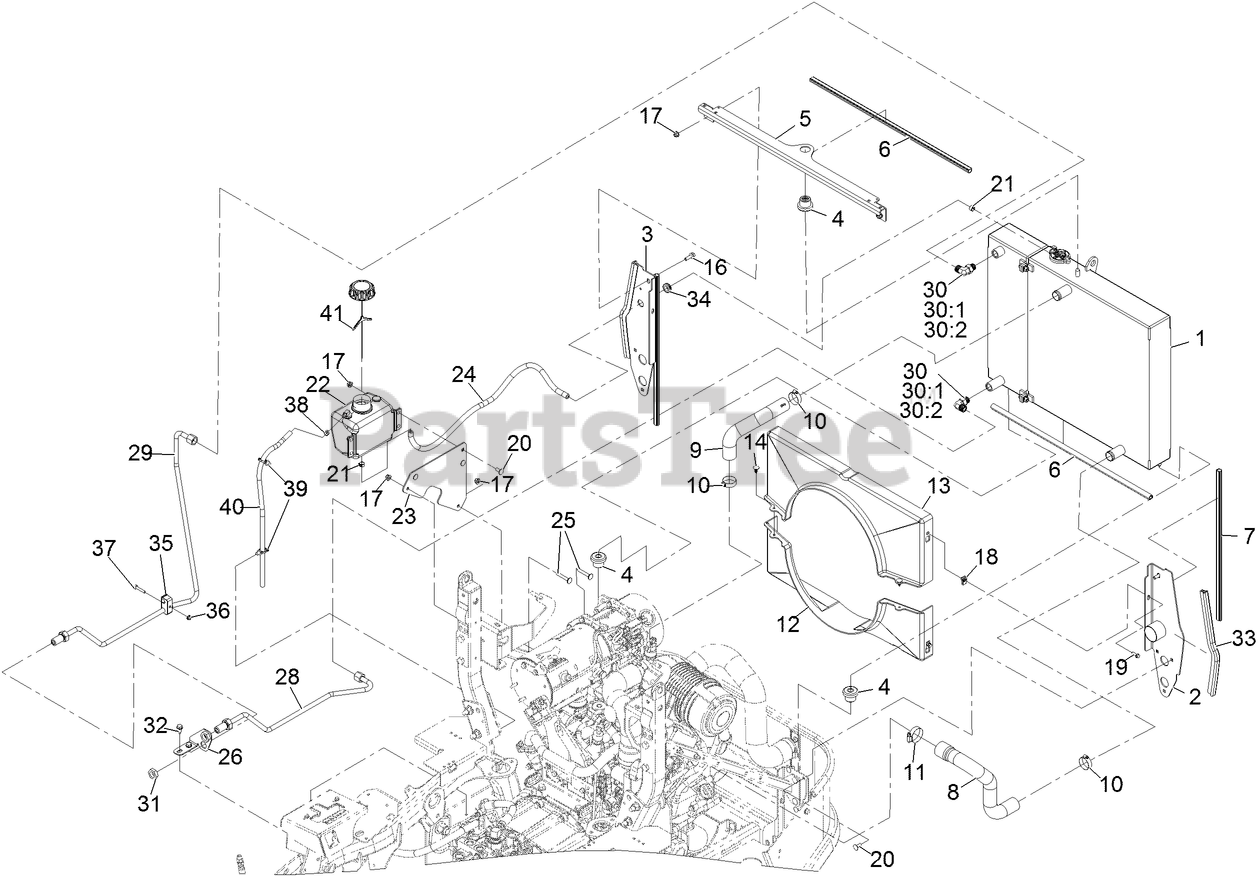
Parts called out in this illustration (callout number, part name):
1	COOLING ASM
2	SUPPORT-RADIATOR, LH
3	SUPPORT-RADIATOR, RH
4	MOUNT-ISOLATOR
5	BRACKET-COOLING, TOP
6	SEAL-BULB
7	SEAL-BULB
8	HOSE-RADIATOR, LOWER
9	HOSE-RADIATOR, UPPER
10	CLAMP-HOSE
11	CLAMP-HOSE
12	SHROUD-BOTTOM
13	SHROUD-TOP
14	PLUG-PLASTIC
16	SCREW-HHF
17	NUT-HF, NI
19	SCREW-HWH
20	SCREW-CARR
21	CLAMP-HOSE
22	TANK-OVERFLOW, W/CAP
23	BRACKET-BOTTLE
25	BOLT-CARR
26	BRACKET-BULKHEAD
28	HYDRAULIC TUBE ASM
29	HYDRAULIC TUBE ASM
30	FITTING-ELBOW, 90 DEG
30:1	O-RING
30:2	O-RING
31	NUT-BULKHEAD
32	SCREW-HWHTF
33	SEAL-BULB
34	GROMMET
35	CLAMP-TWIN
36	NUT-HF
37	SCREW-HH
38	CLAMP-HOSE
39	CLIP-TIE
40	HOSE-FUEL
41	CAP-W/TETHER
